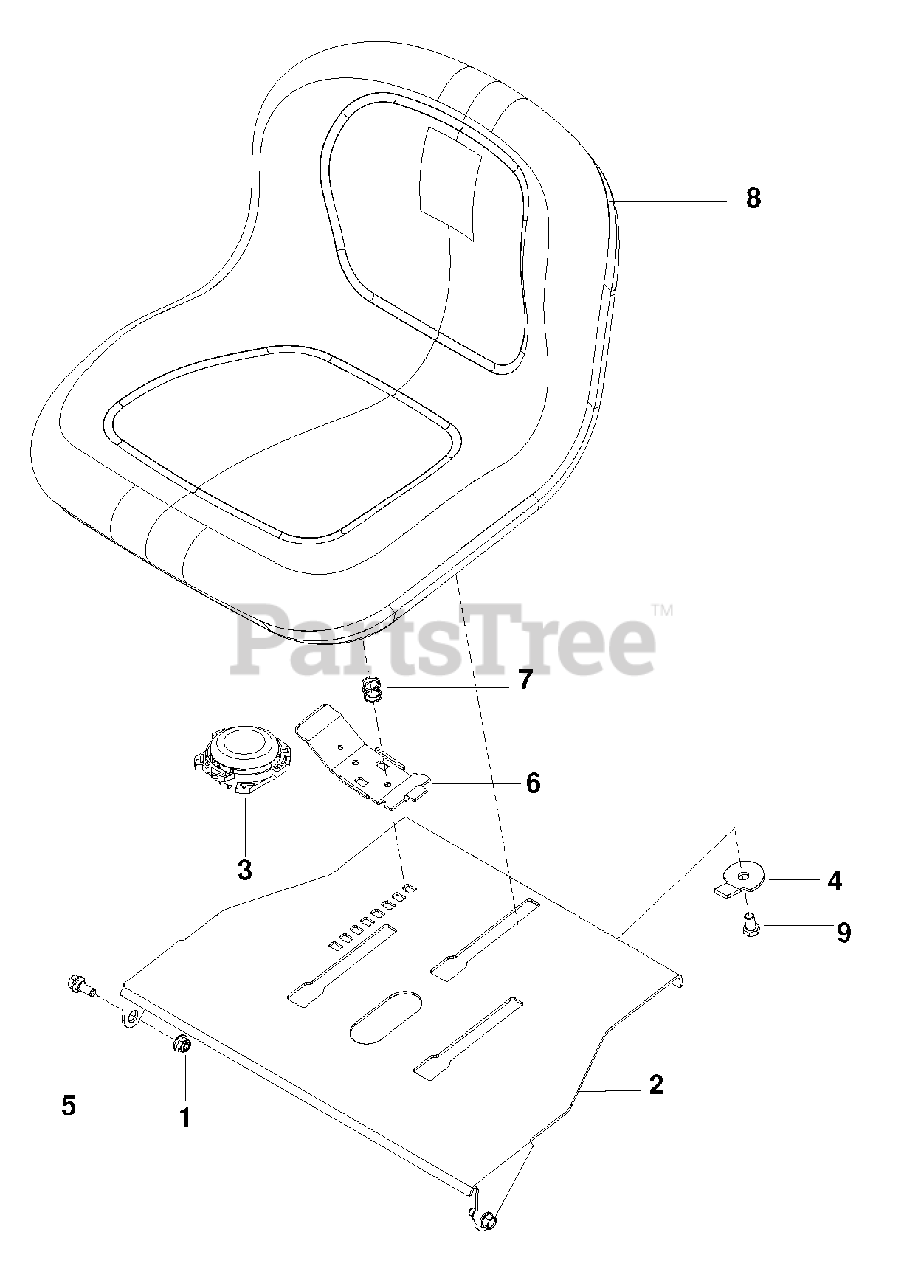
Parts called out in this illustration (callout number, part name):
1	NUT 5/16-18 FLANGE NYLOC
2	PLATE, SEAT
3	SWITCH, SEAT N/C
4	STOP, SEAT
5	BOLT 5/16-SHOULDER
6	HANDLE, SEAT SLIDE
7	SPRING, SEAT SLIDE
8	SEAT
9	HCS 3/8-16 x 5/8
